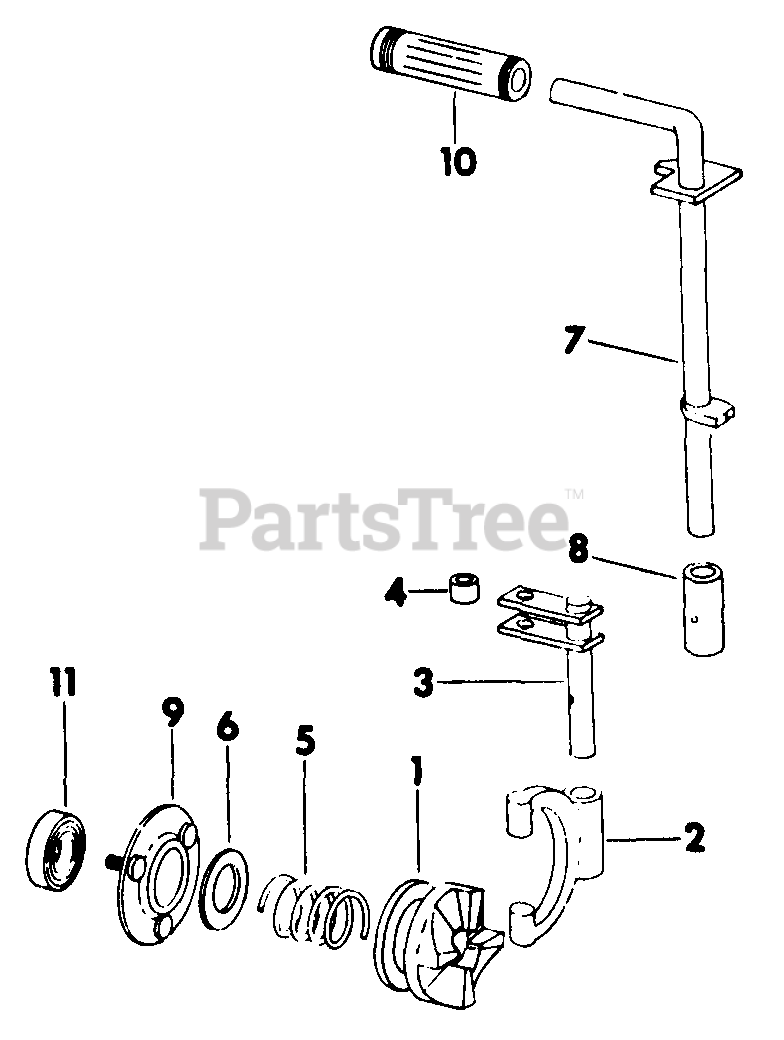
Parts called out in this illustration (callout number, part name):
1	CLUTCH, DRIVEN
2	FORK, CLUTCH
3	SHAFT, CLUTCH FORK
5	SPRING, CLUTCH RETAINING
6	WASHER, .762 X 1.375 X 16 GA HARDENED
7	SHAFT, CLUTCH CAM
8	SPACER, BUSHING
9	PLATE, BEARING RETAINER BACK
10	GRIP, HANDLE
11	BEARING, BALL
